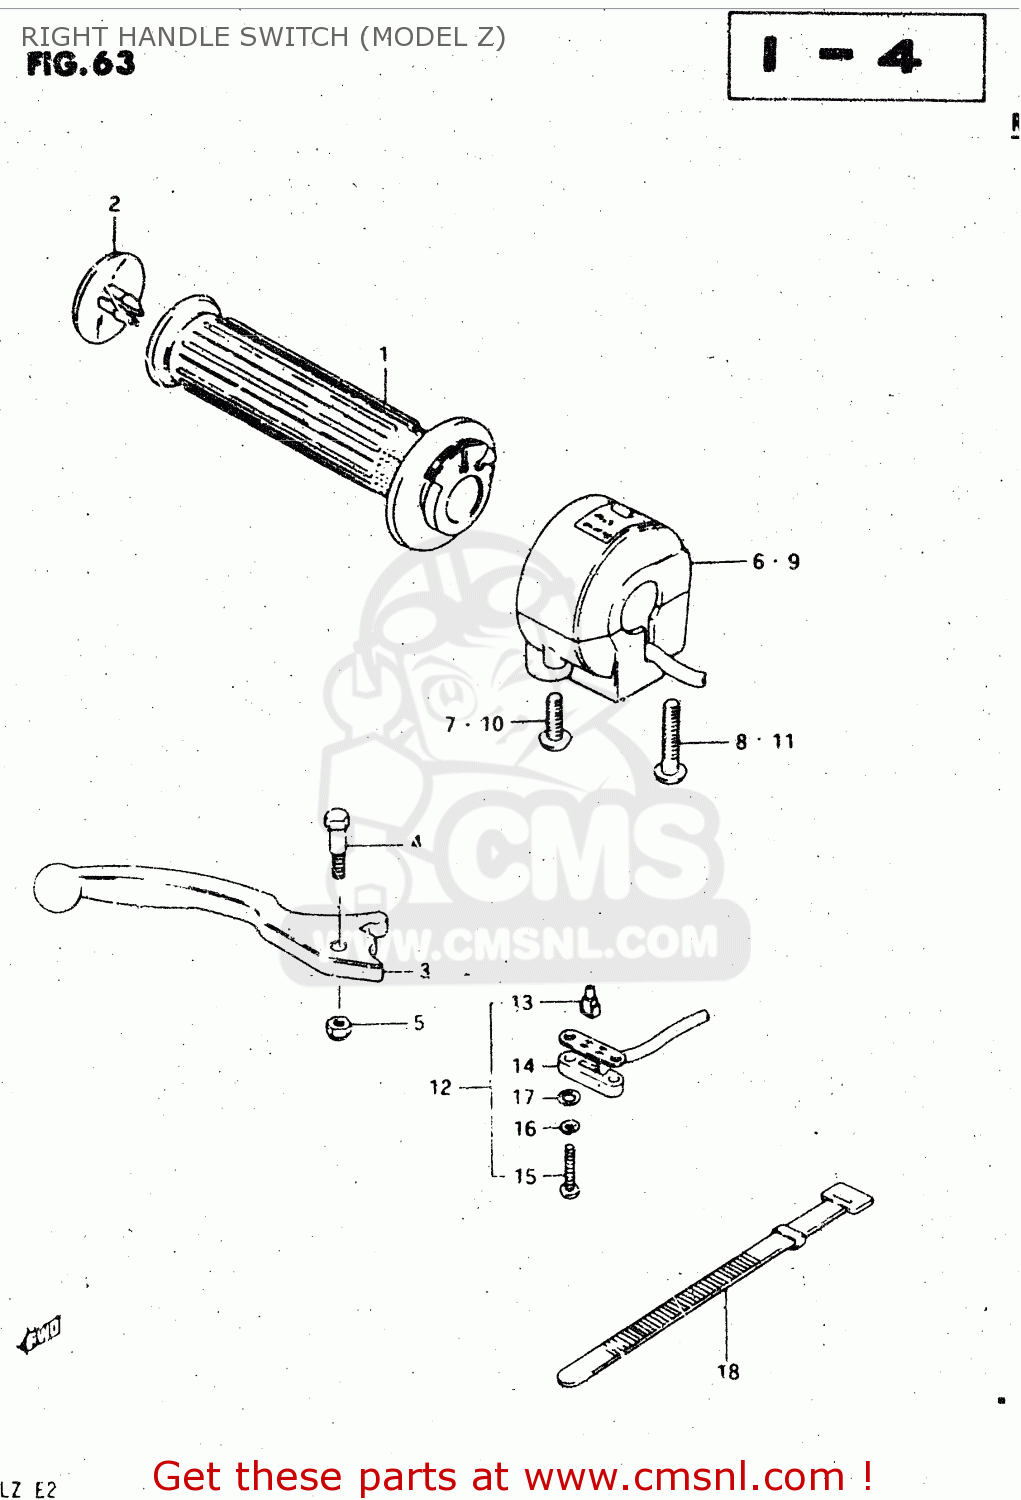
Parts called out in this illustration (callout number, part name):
1	GRIP,THROTTLE
2	CAP,GRIP END
3	LEVER,BRAKE
4	BOLT
5	NUT 6MM
6	SWITCH ASSY, HANDLE RH
7	SCREW
8	SCREW
9	SWITCH ASSY,HANDLE,R
10	SCREW
11	SCREW
12	SWITCH ASSEMBLY
13	CONTACT,SWITCH
14	COVER,FR BK TERMINAL BASE
15	SCREW
16	LOCK WASHER
17	WASHER
18	CLAMP(L:120)
